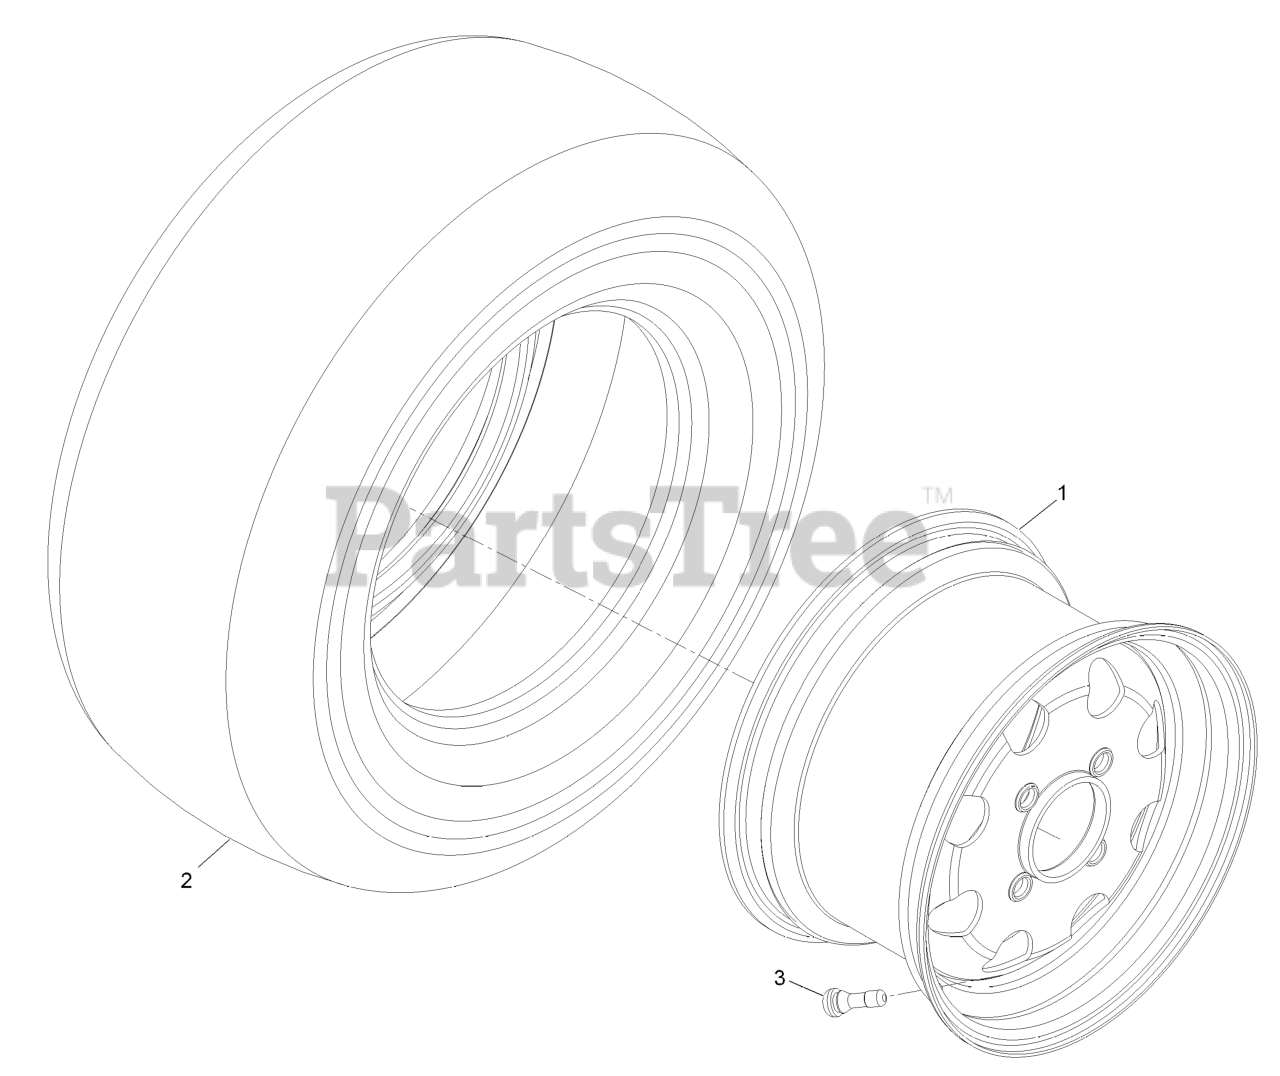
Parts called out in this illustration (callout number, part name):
1	RIM ASM
2	TIRE-STANDARD
3	Stem-Valve
